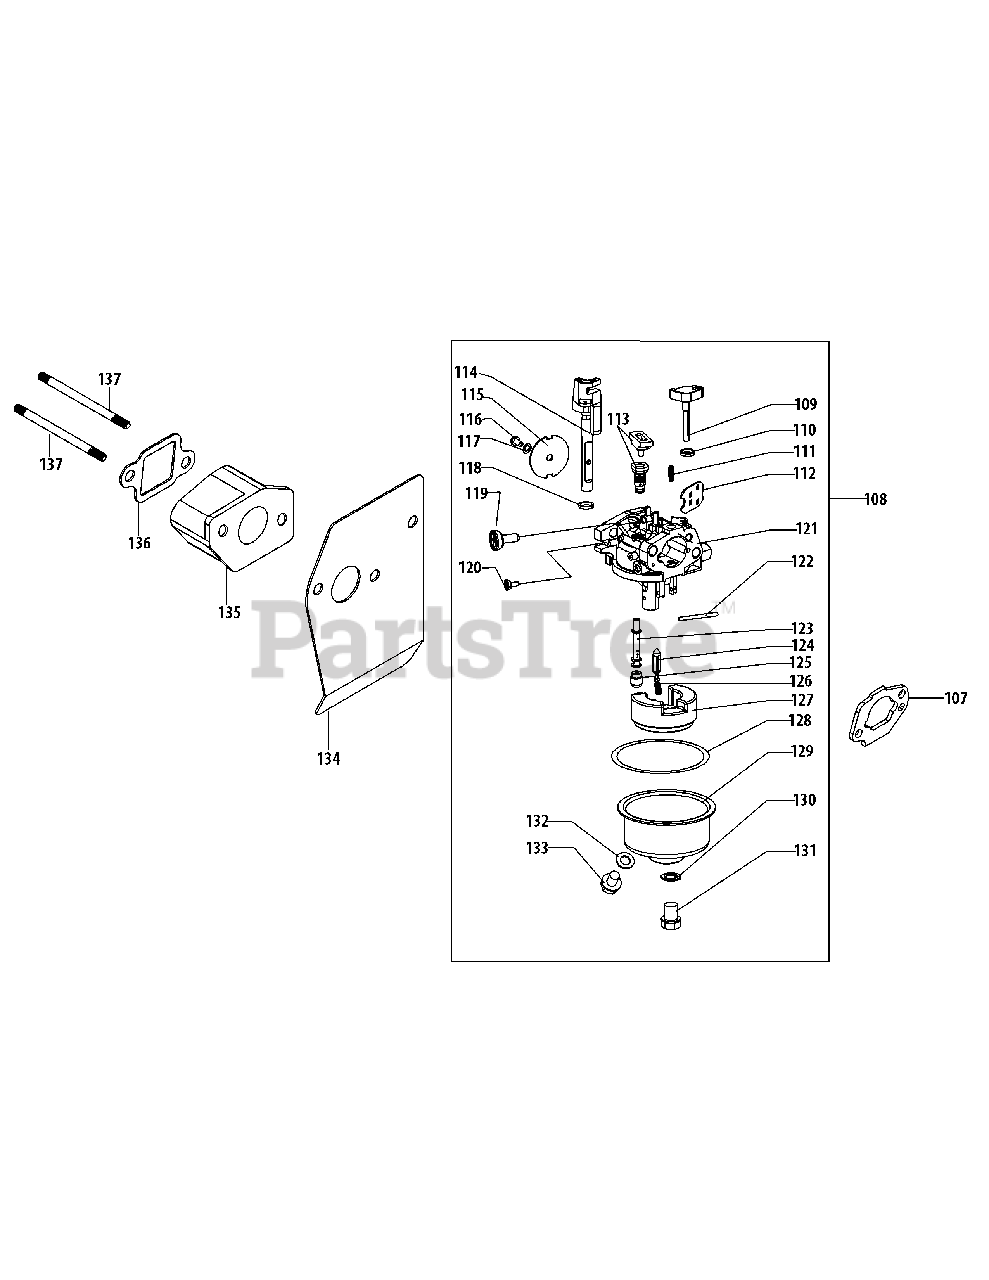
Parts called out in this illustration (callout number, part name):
107	Carburetor Gasket Plate
108	Carburetor Assembly
109	Choke Shaft
110	Fiber O-Ring
111	Choke Plate
112	Choke Return Spring
113	Idle Jet Assembly
114	Throttle Shaft
115	Throttle Plate
116	Lock Washer
118	Fiber O-Ring
119	Idle Speed Adjusting Screw
120	Idle Mixture Screw
121	Carburetor Body
122	Float Pin
123	Emulsion Tube
124	Needle Valve
125	Main Jet
126	Needle Valve Spring
127	Float
128	Fuel Bowl O-Ring
129	Fuel Bowl
130	Fuel Bowl Gasket
131	Fuel Bowl Mounting Bolt
132	Fuel Drain Plug Gasket
133	Fuel Drain Plug
134	Carburetor Gasket
135	Carburetor Insulator
136	Carburetor Insulator Gasket
137	Carb Stud M6×113
